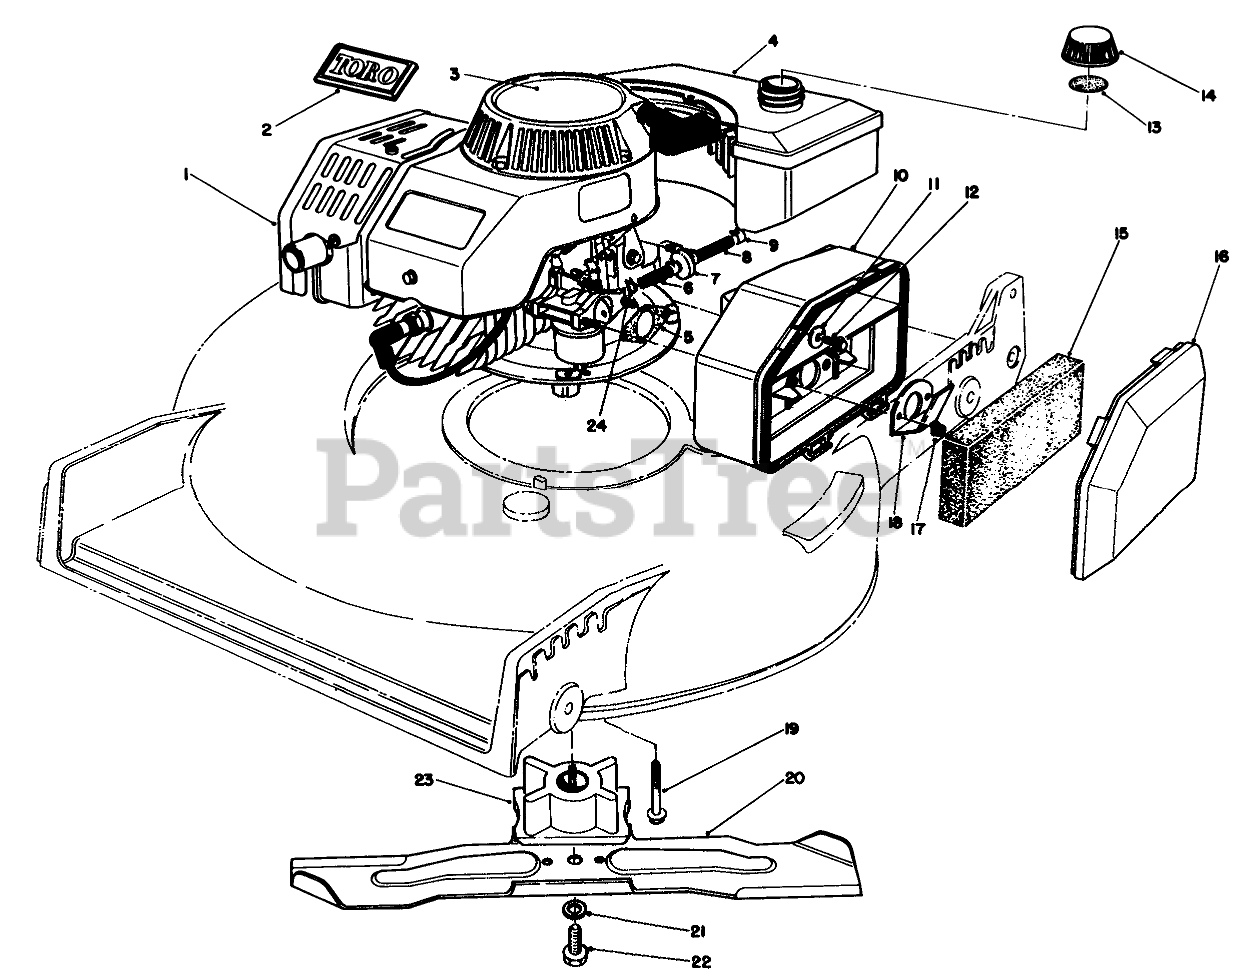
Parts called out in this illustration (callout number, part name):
1	Engine
2	TORO LOGO PLT
3	DECAL- 2 CYC RECOIL
4	Gas Tank Assembly
5	GASKET-AIR CLEANER
6	HOSE-FUEL
7	FILTER-FUEL
8	HOSE-FUEL
9	CLAMP-FUEL LINE
10	AIR CLEANER
11	WASHER-FLAT
12	SCREW-HH
13	GAS CAP GASKET
14	Gas Cap Assy. (Incl. Ref. #13)
15	FILTER
16	AIR CLEANER COVER
17	NUT-LOCK
18	SPIT BACK DEFLECTOR
19	SCREW-HHF
20	BLADE-21in
21	WASHER-LOCK
22	SCREW-BLADE
23	Retainer Blade
24	CLAMP-HOSE
